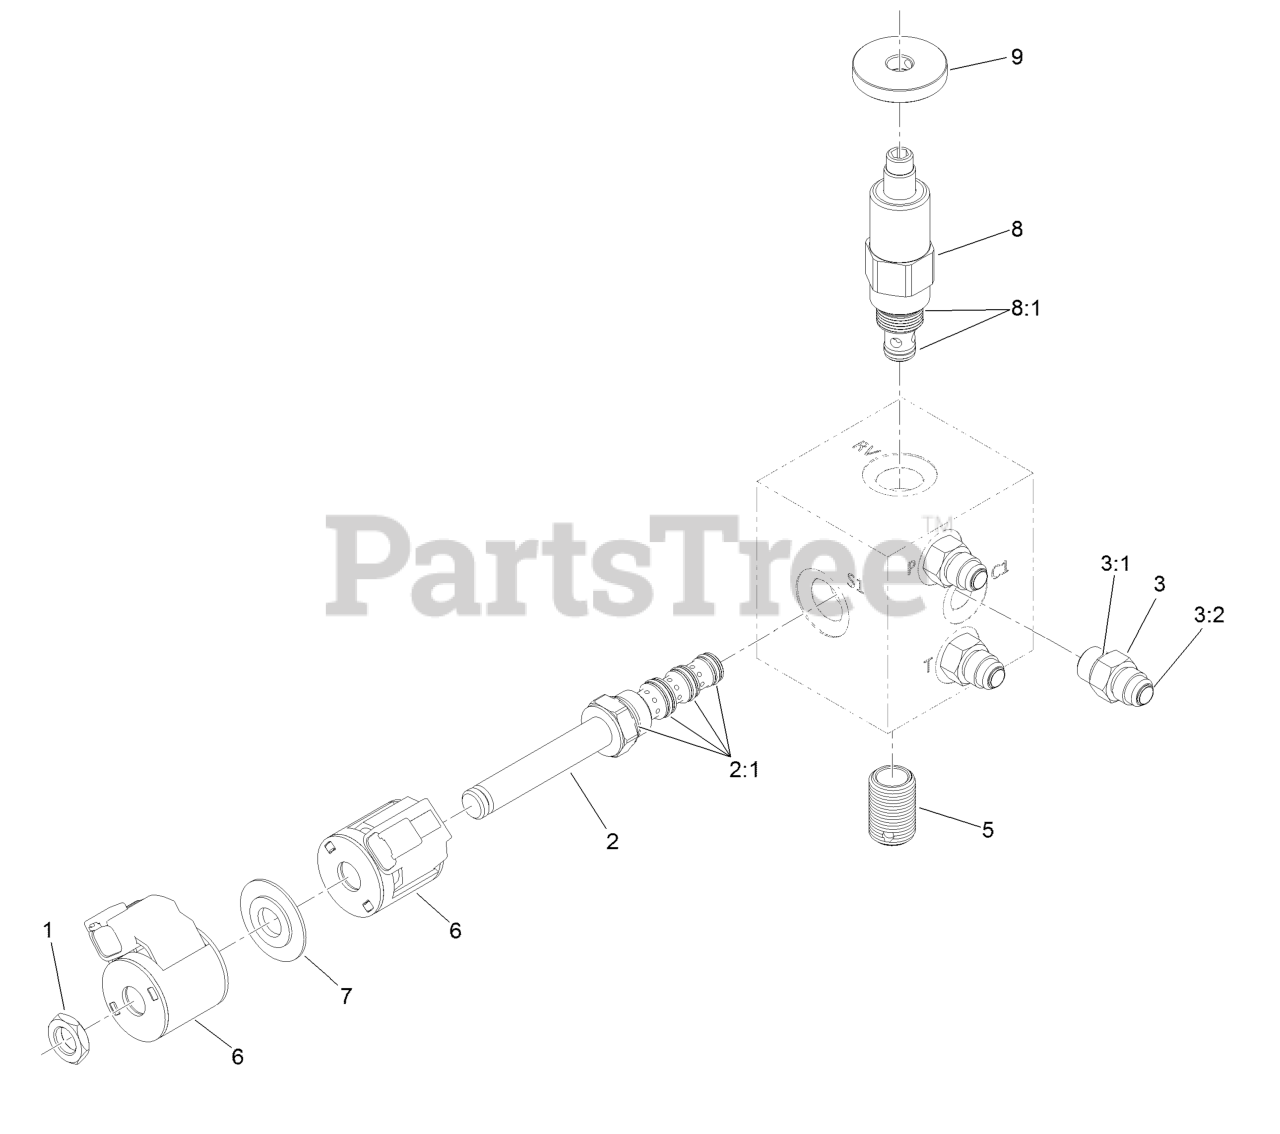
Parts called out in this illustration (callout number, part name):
1	Nut-Coil
2	Valve-Solenoid
2:1	Seal Kit
3	Fitting-Straight
3:1	O-Ring
5	Nipple-Filter
6	Coil-Solenoid
7	Spacer-Coil
8	Valve-Relief, Poppet Type
8:1	Seal Kit
9	Knob (1.5 DIA)
